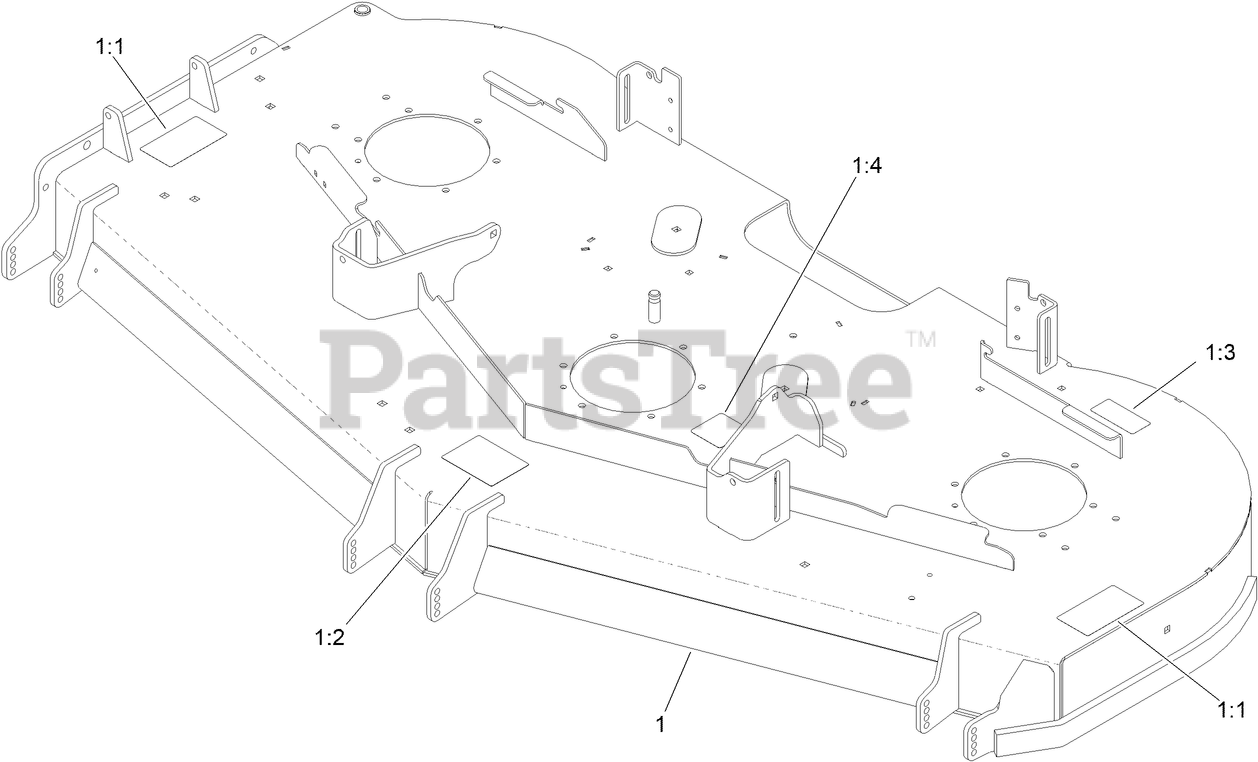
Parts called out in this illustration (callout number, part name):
1	Deck ASM W/Decals
1:1	DECAL-DANGER
1:2	DECAL-SCALP, ANTI
1:3	DECAL-BOLT TORQUE
1:4	DECAL-ROUTING, BELT
